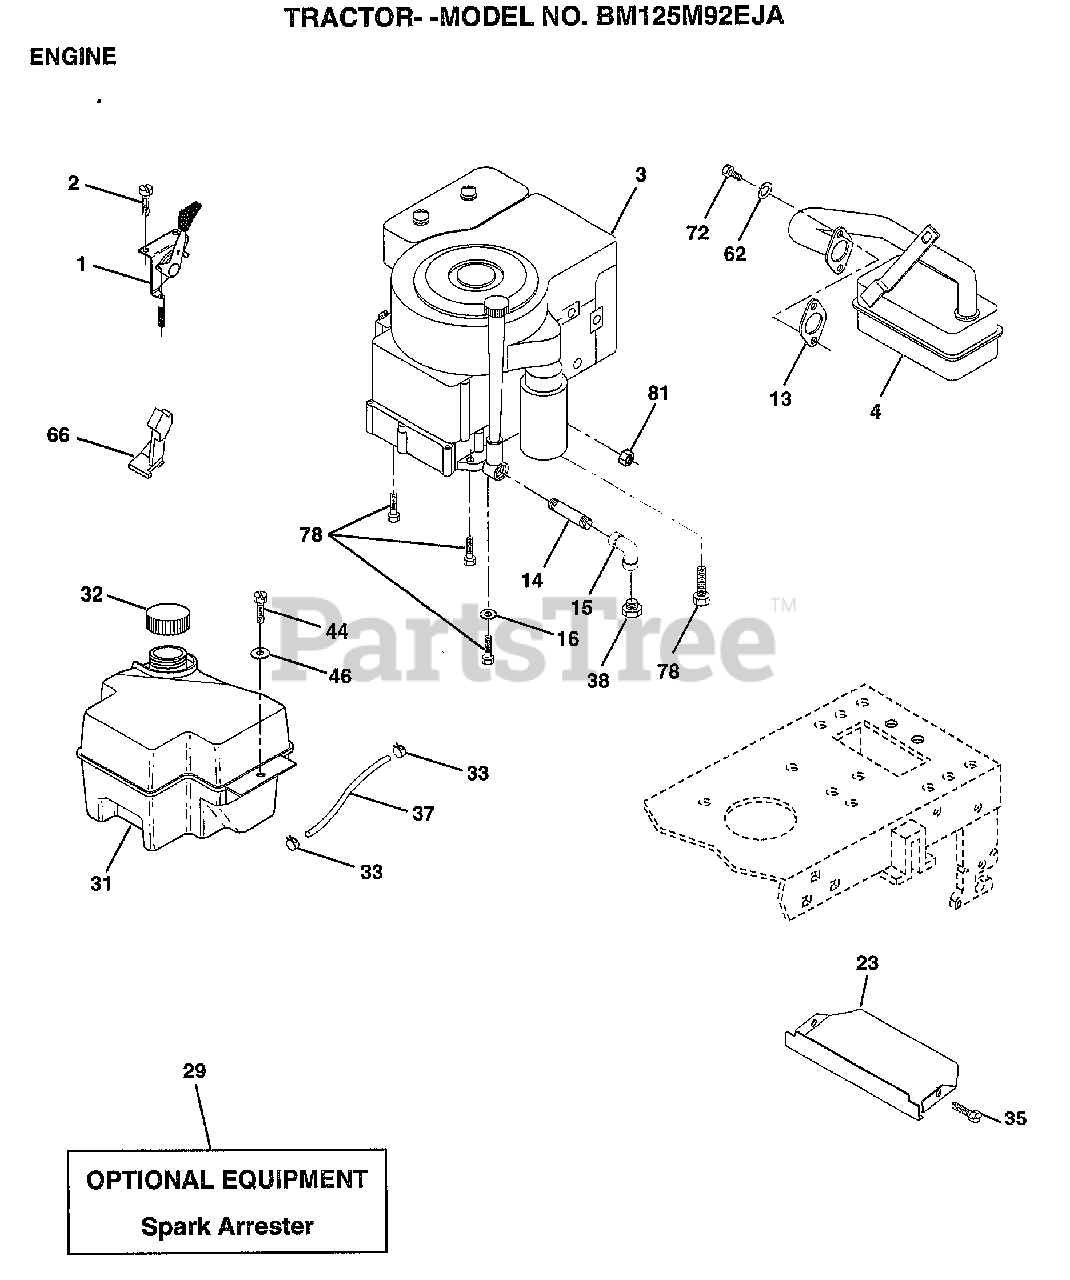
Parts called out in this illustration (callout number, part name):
1	CONTROL.THTL.23.5
2	SCREW LT
4	MUFFLER
14	PIPE NIPPLE
15	ELBOW
16	LOCKWASHER
23	SHIELD.BRN/DBR.GD
31	TANK.FUEL.FRONT.
32	CAP ASM FUEL
33	HOSE CLAMP
35	SCREW
37	LINE FUEL
44	SCREW HEX CRT
46	WASHER
62	LOCKWASHER
66	"STOP,DASH THROTT"
72	SCREW
78	SCREW
81	NUT
